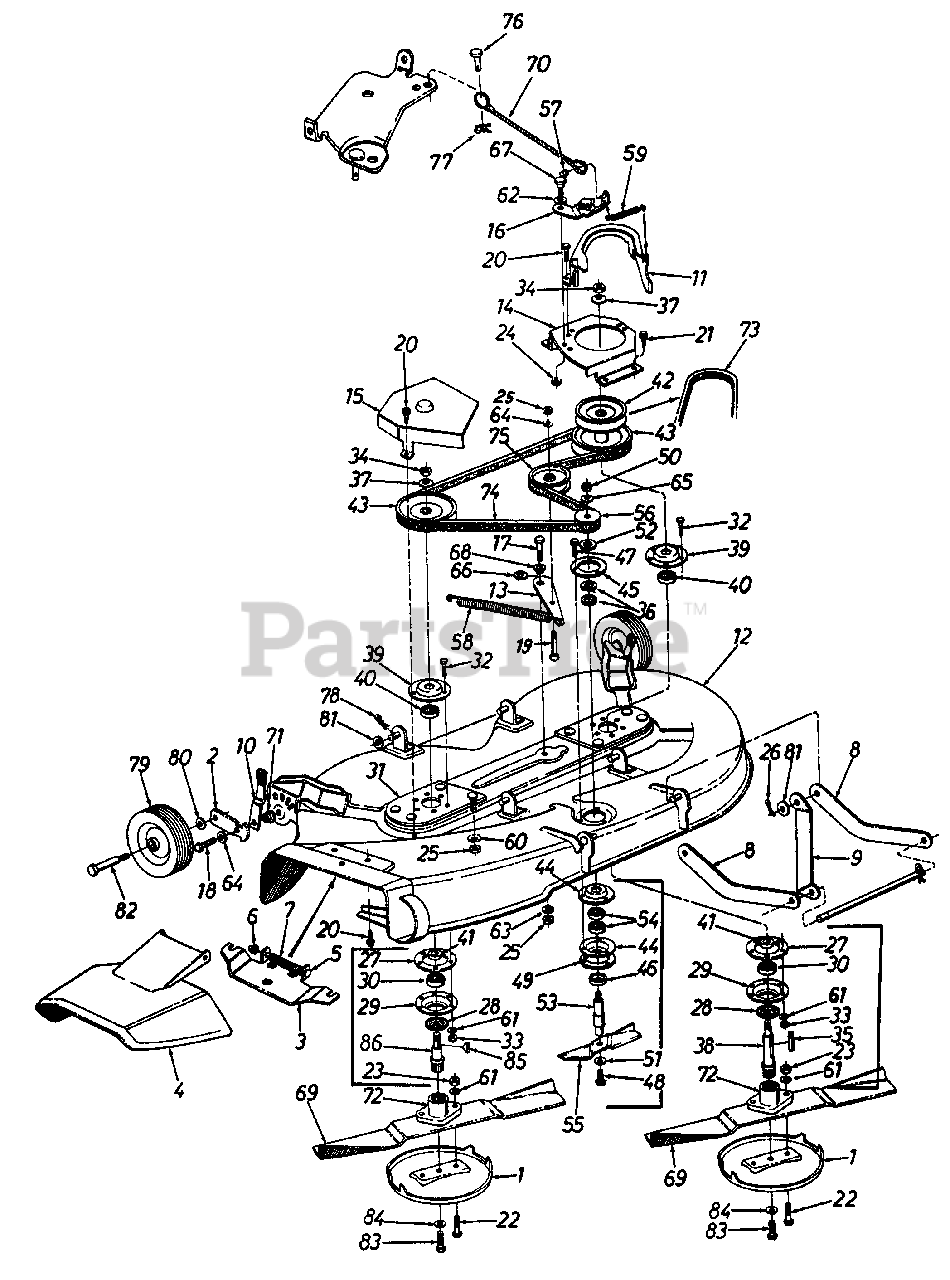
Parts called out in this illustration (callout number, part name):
1	Anti-Scalp Plate
2	Wheel Pivot Bar
4	Chute Cover Ass'y.
6	Cap Speed Nut 1/4" Rod.
7	Torsion Spring
11	Belt Guard
12	44" DeckAss'y.
13	Idler Bracket
14	Pulley Cover L.H.
17	Hex Bolt 3/8-24 x 1.00"*
18	Hex Bolt 3/8-24 x 1.25" Lg.*
19	Hex Bolt 3/8-24 x 1.50" *
20	Hex Wash. S-Tapp Scr. 1/4-20 x .50"
21	Hex Wash. Hd. Tapp Scr. 5/16-18 x .75" Lg.
22	Hex Bolt 5/16-24 x 1.25" (Grade 5)
23	Hex Nut 5/16-24 Thd.*
24	Hex Cent. L.-Nut 5/16-18 Thd.
25	Hex Nut 3/8-24 Thd.*
26	Cotter Pin 3/32 Dia. x 1.00" Lg.
27	Reinforcement Plate
28	Bearing Shield
29	Open Brg. Housing 1.85 I.D.
30	Ball Brg. .787 I.D. x 1.85 O.D. x .551
31	Spindle Mounting Plate Ass'y.
32	Hex Bolt 5/16-24 x 1.0" Lg.
33	Hex Nut-5/16-24
34	Hex Jam Nut 5/8-18 Thd.
35	Square Key 3/16 x 2.25" Lg.
36	Fl-Wash. 5/8" I.D. x 15/16" O.D.
37	Bell. Wash. .630 I.D. x 1.25 x 090
38	44" Deck Blade Spindle
39	Bearing Housing 1.85 I.D.
40	Ball. Brg. .787 I.D. x 1.85 O.D. x .551
41	Spacer 1.0 O.D. x .790 I.D., .350 Lg.
42	5/8 "V"-Pulley .79 I.D. x 5.75 O.D.
43	"V"-Pulley .79 I.D. x 6.50 O.D.
44	1-3/8" I.D.-Bearing Housing
45	Reinforcement Plate
46	Bearing Shield
47	Hex "B" Tap Scr. .250 x .750 Lg.
48	H ex Cl.-Scr. 3/8-24 x .88 Lg.
49	Reinforcement Plate
50	Hex Jam Nut 1/2-20 Thd.
51	Bell.-Wash. .400 I.D. x .88 O.D. x .060
52	Fl.Wash. .635 x 1.04 O.D. x .120"
53	6. 5" Blade Spindle
54	Ball Brg. .62 I.D. x 1.30 O.D. x 44"
56	1/2" V Pulley Half .625 I.D. x 2.25" O.D.
57	Cap Speed Nut 1/4" Rod.
58	Extension Spring .73 O.D. x 4.31 Lg.
59	Extension Spring .38 x 2.75" Lg.
60	Bell.-Wash. .400 I.D. x .88 O.D. x .060
61	L.-Wash. 5/16" I.D.*
62	Spring Wash. .445 I.D. x .75 O.D. x .017
64	Bell.-Wash. .400 I.D. x 1.13 O.D. x .030
65	Bell.-Wash. .505 I.D. x 1.00 O.D. x .075
66	Spring Wash. .650 I.D. x .875 O.D. x .015 Thk.
67	Shld. Bolt.437 Dia. x .180
68	Shld. Spacer.625 I.D.
69	Mower Blade 21.88
70	Brake Cable Ass'y.
71	Shld. Spacer
72	Blade Adapter
73	"V"-Belt 1/2 x 56" Lg.
74	"V"-Belt 1/2 x 74"Lg.
75	Fl.-ldler w/ Flanges 3.50 O.D.
76	Clevis Pin 1/4 Dia. x .53 Lg.
77	Intern. Cotter Pin 5/16 " Dia.
78	Intern. Cotter Pin 1/2" Dia.
79	Deck Wheel 6.0 x 1.38
80	Bell.-Wash. .400 I.D. x .88 O.D. x .060
81	Fl.-Wash. .531 I.D. x .93 O.D. x .090
82	Shoulder Bolt 3/8-16 x 1.41
83	Hex Bolt 3/8-24 x .88" Lg.
84	L.-Washer 3/8 I.D.*
85	Sq. Key 3/16 x .75" Lg.
86	44" Deck Blade Spindle
